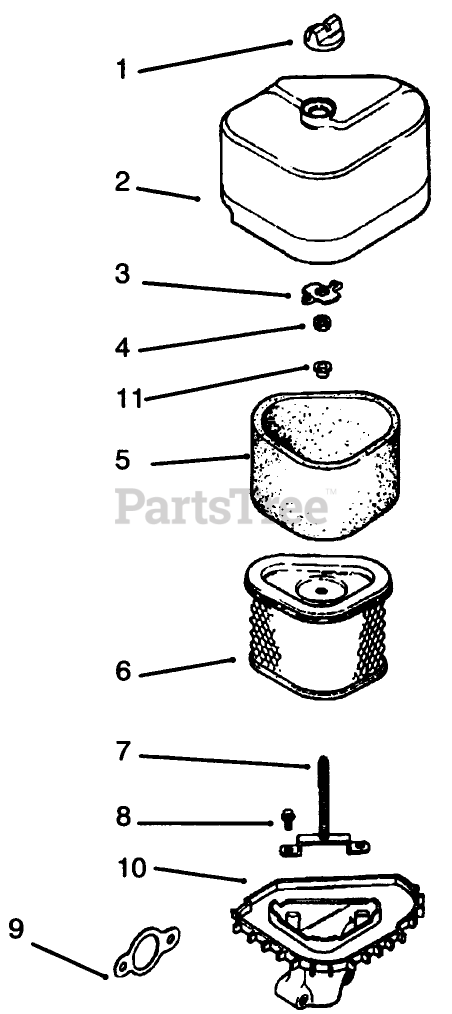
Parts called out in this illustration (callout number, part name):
1	Knob-Air Cleaner Cover
2	Cover-Air Cleaner
3	Nut-Wing
4	Washer
5	Element-Air Cleaner (Only On: 72042, 72043, 72062, 72063)
6	Precleaner-Element (Only On: 72042,72043,72062,72063)
7	Stud M-6x1.0x66
8	Screw-Mounting Plate
9	Gasket-Air Cleaner (Only On: 72042, 72043, 72062, 72063)
10	Base-Air Cleaner (Incl.
11	Grommet
